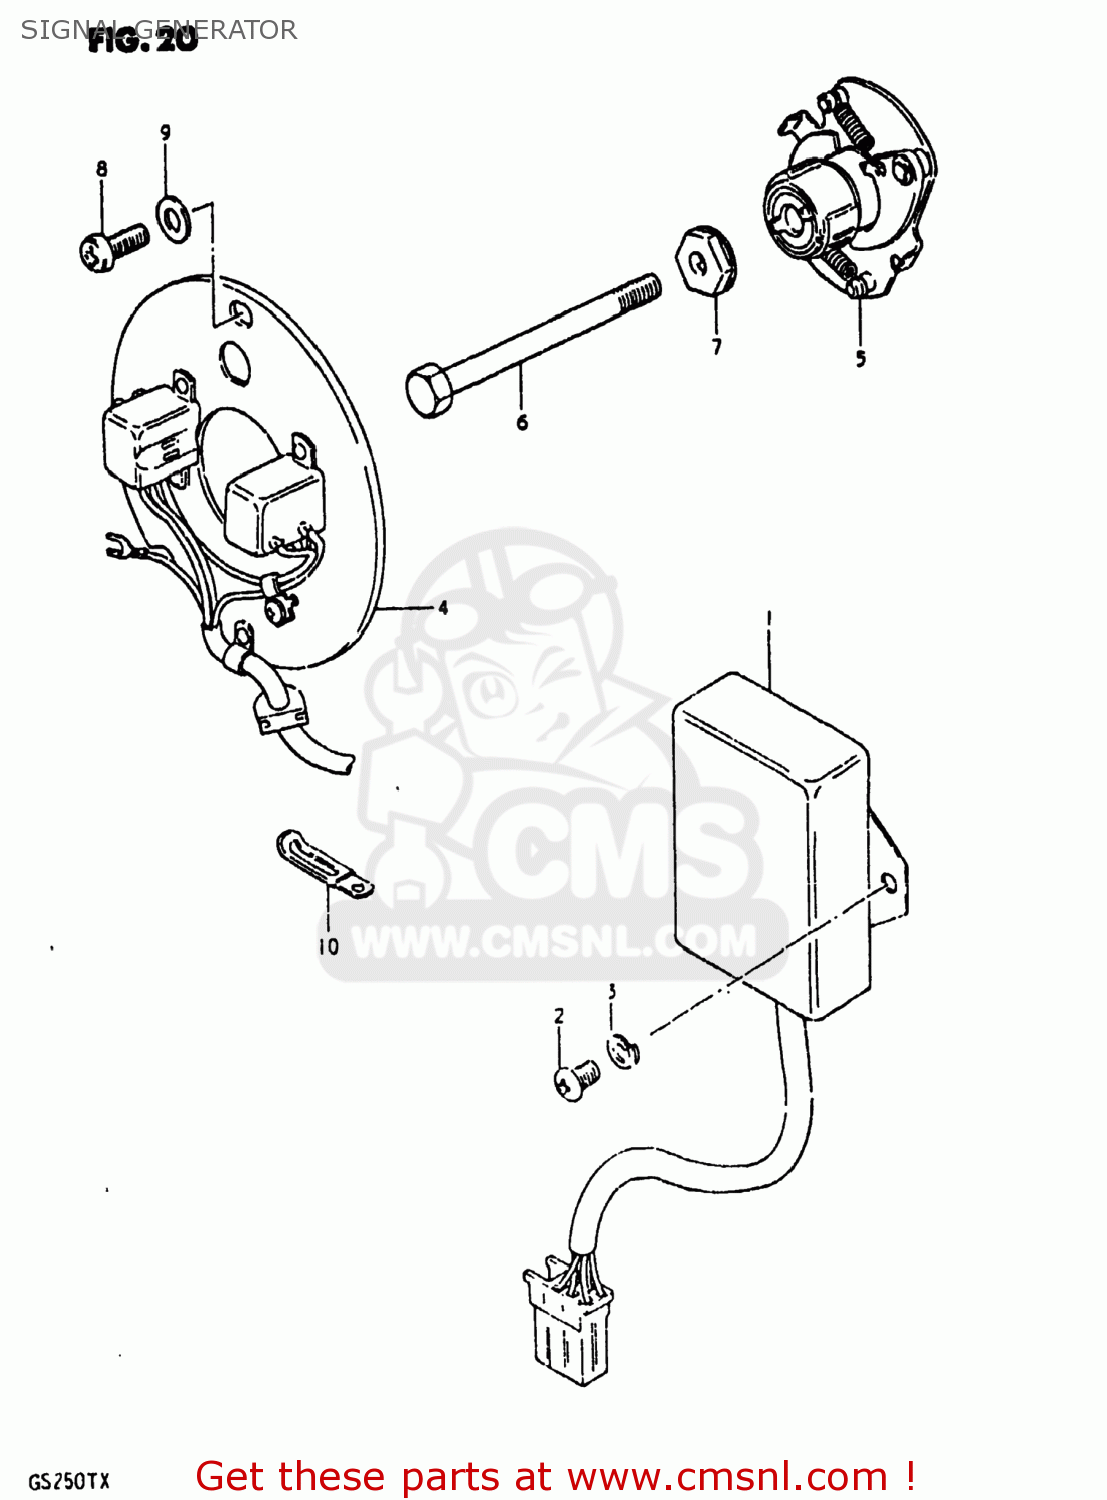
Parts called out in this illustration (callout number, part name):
1	CDI UNIT KOKUSAN
2	SCREW
3	LOCK WASHER
4	SIGNAL GENERATOR ASSEMBLY
5	GOVERNOR ASSEMBLY
6	BOLT 6X60
7	WASHER,CONTACT BREAKER
8	SCREW(5X12)
9	WASHER
10	CLAMP L:35
